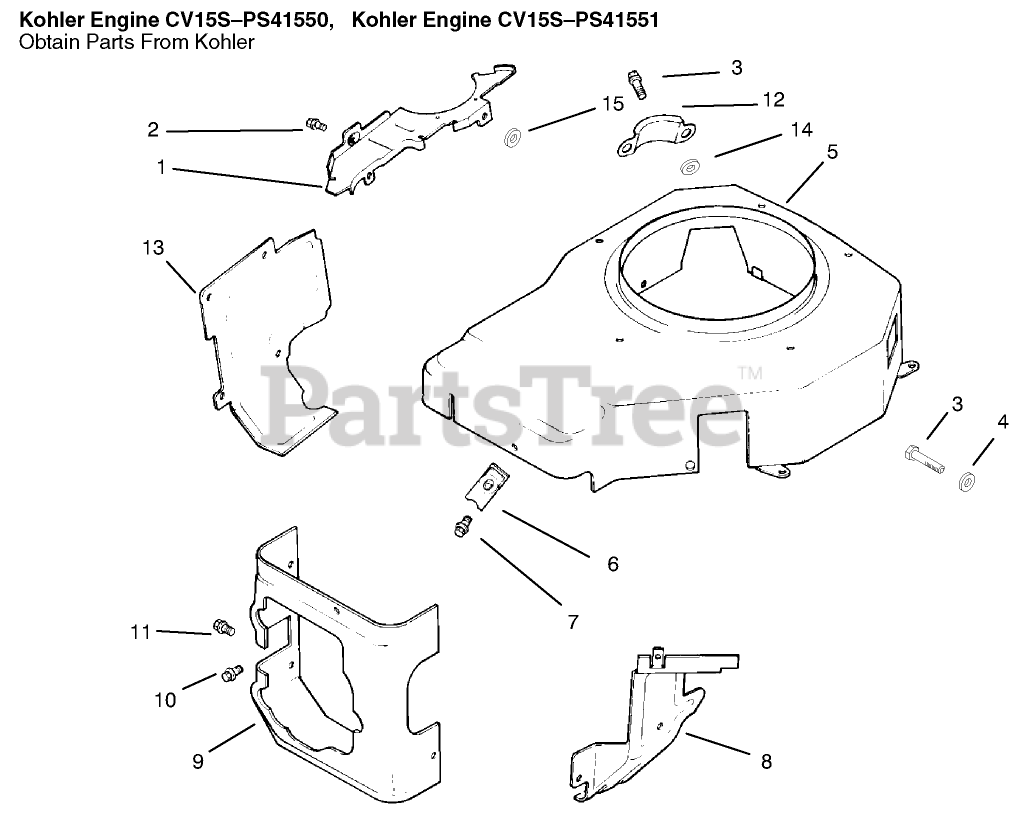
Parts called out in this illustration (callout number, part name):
1	Plate-Blower Housing (Only On: 72042,72043,72062,72063)
4	Washer
5	Housing-Blower
8	Baffle-Carburetor (Only On: 72042, 72043, 72062, 72063)
9	Baffle-Cylinder Head (Only On: 72042, 72063, 72062, 72043)
12	Cover-Pinion
13	Baffle-Cylinder Barrel (Only On: 72042, 72063, 72062, 72043)
14	Washer
